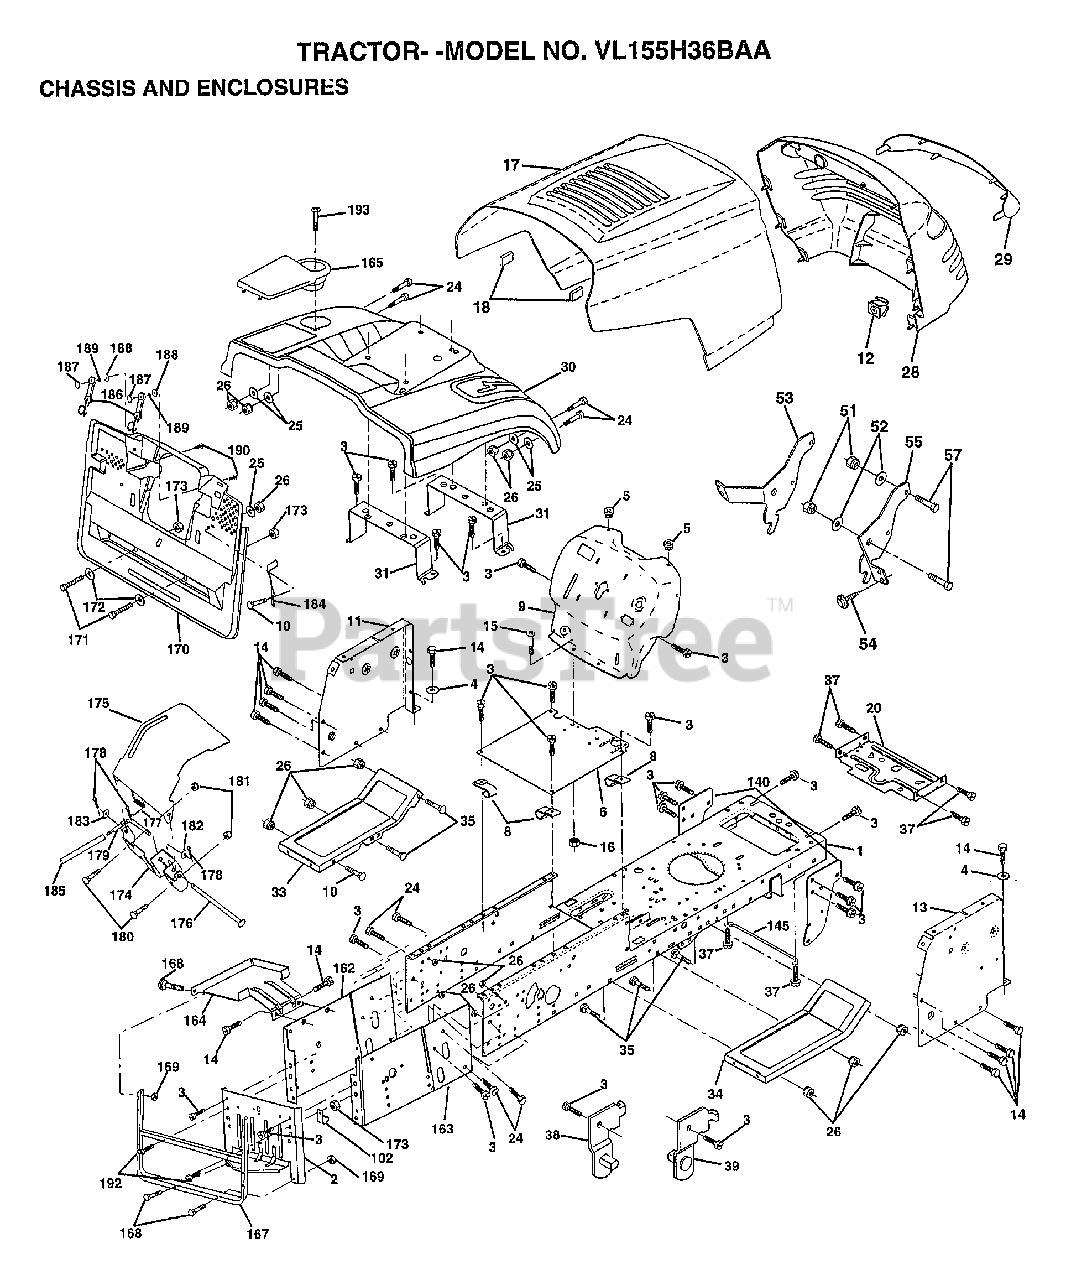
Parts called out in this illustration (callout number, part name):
1	CHASSIS.STAMPING
2	DRAWBAR.CRD
3	SCREW
4	WASHER
5	BUMPER-HOOD/DASH
6	SADDLE
8	"CLIP,INSULATOR"
9	DASH.SILKSCREEN
11	"PANEL-DASH,LH"
12	CLIP.TINNERMAN
13	"PANEL-DASH,RH"
14	SCREW LT
15	SCREW
17	HOOD
20	"PLATE-MTG,BATT/FU"
24	BOLT
25	WASHER
26	NUT
29	LENS.GRILLE
30	FENDER.GEAR.CRD.GREEN
31	BRKT.SUPT.FENDER.CRD
33	FOOTREST.LH.LT/GT
34	FOOTREST.RH.LT/GT
35	BOLT
37	SCREW LT
38	BRACKET ASM LH
39	BRACKET ASM RH
51	NUT
52	WASHER
53	BRACKET.GRILLE.LH
54	SCREW.HEX.WS.HD
55	BRACKET.GRILLE.RH
102	CLIP T
140	BRKT SUSPENSION
145	"ROD POVOT,CHASSIS"
148	SCREW
162	BRKT.EXT.CHASSIS.LH.CRD
163	BRKT.EXT.CHASSIS.RH.CRD
164	SUPPORT.BATTERY.CRD
165	COVER.BATTERY.CRD.BLACK.LT
167	SUPT.ASM.BACKPLATE
168	BOLT-RD HD SQ NK
170	COVER.BACKPLATE.BLACK
171	BOLT.HEX.3/8-16X2-1/2
173	NUT
174	BRKT.SWITCH.FBI.CRD
175	GRUARD.DOOR.REAR.CRD
176	HINGE PIN
177	SPRING.COVER.LH
179	ROD.PIVOT.FBI.CRD
182	WASHER.385X.625
183	WASHER
184	BRKT.ACTUATOR.BAG.CRD
185	TUBE.LEVER.SWCH.FBI.CRD
186	LATCH ASSY.BAGGER
187	WELDNUT
188	WASHER #10
189	LOCKWASHER
190	SCREW
192	SCREW LT
193	SCREW LT
